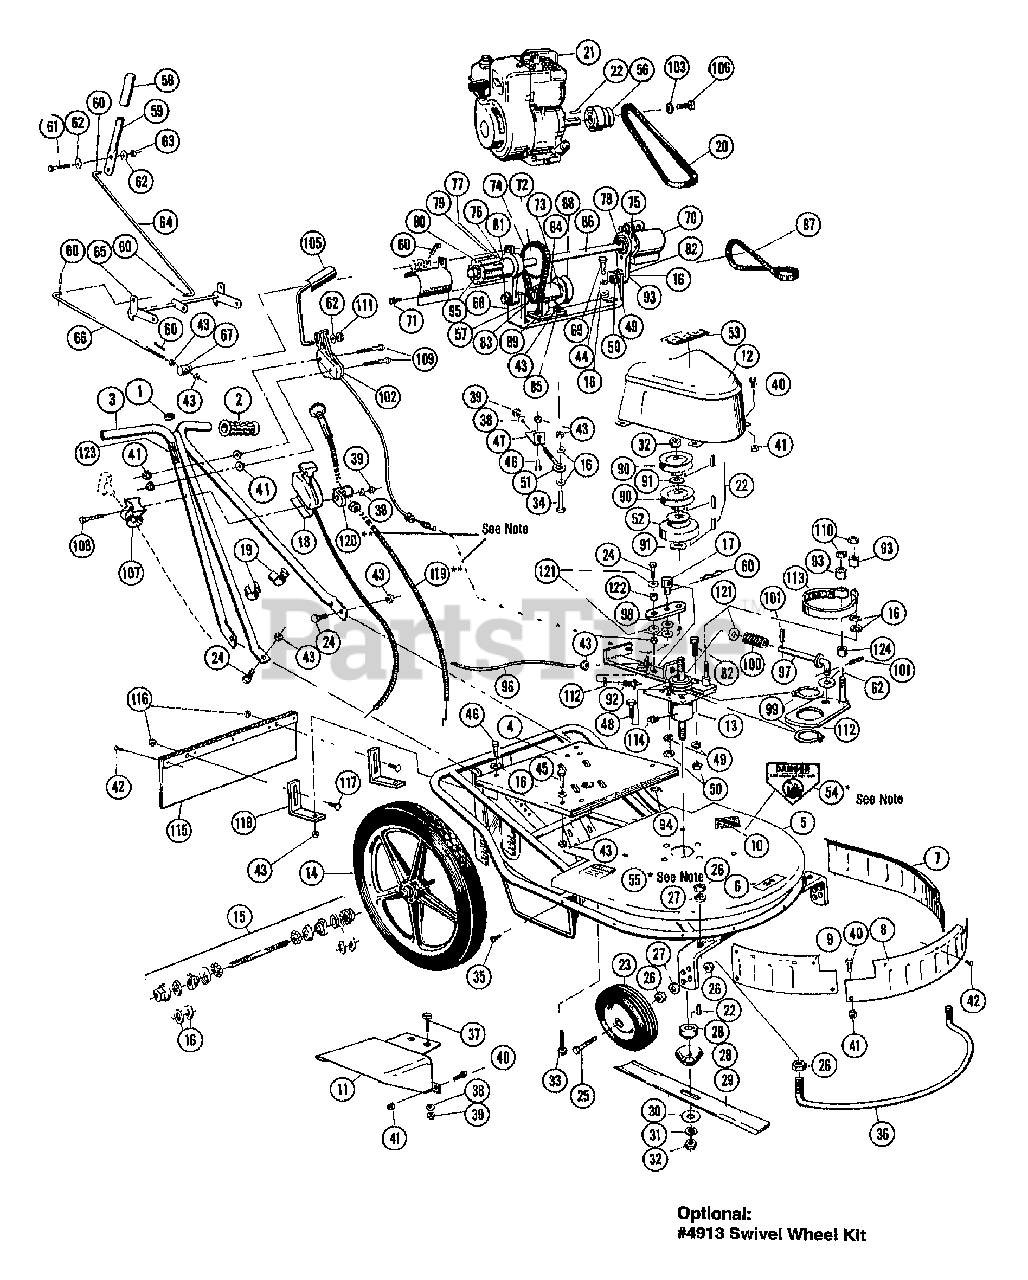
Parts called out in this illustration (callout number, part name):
1	PLUG-HANDLE
2	GRIP-HANDLE
3	ASSM-HANDLE 24"
4	BOARD-MOTOR
4	BASE-MOTOR 7HP 24"
6	CUTTING WIDTH DECAL 24"
7	GUARD-LEFT 20" & 24"
8	GUARD-FRONT 24"
9	GUARD-RIGHT
10	DECAL-CAUTION
11	DEFLECTOR-DISCHARGE
12	HOOD-MOWER
13	ASSM-24" SPINDAL
13	HOUSING-SPINDLE 24"
13	SHAFT-SPINDLE 24"
14	ASSM-WHEEL 20" W/KNOBBY
14	ASSM-WHEEL 20" W/O TIRE
14	TIRE-20" KNOBBY
15	DUST COVER SET (2)
16	WASHER-FLAT 5/16 SAE
17	PIN-CONNECTING ROD
18	CABLE-THROTTLE 24"
19	CLIP-THROTTLE CABLE
20	BELT-ENGINE #434-24"
21	ENGINE, BRIGGS 5HP #130202
21	ENGINE, BRIGGS 5HP, IC SERIES #131232
21	ENGINE, BRIGGS 7HP #170402
22	KEY-3/16-1/2
22	KEY-1/4 X L
23	WHEEL-FRONT 6"
24	SCR-HH 5/16-18X1.0 G5 ZP
25	SCR-HH 1\2X2.75
26	NUT-HEX JAM 1/2-13
27	WASHER-LK .5
28	KIT-BLADE ADAPTER
28	BLADE ADAPTER NUT
28	BEARING GUARD
29	BLADE-REPL 24" PRO MWR
30	WASHER-FLAT 5/8
31	WASHER-LK .625 ZP
32	NUT-5/8 HEX
33	SCR-HH 5/16-18X2.25 G5ZP
34	SCR-HH 5/16-18X2.5
35	SCR-#14 X .75
36	BUMPER-FRONT 24"
37	SCR-HH 1/4-20 X .625
38	WASHER-LK .25 ZP
39	NUT-HEX 1/4-20 ZP
40	SCR-HH #10-24X.375
41	NUT-3/16 HEX LOCK
42	POP RIVET
43	NUT 5/16-18
44	WASHER-LK .312 ZP
45	SCR-HH 5/16-18X1.5 G5 ZP
46	SCR-HH 5/16-18X1.75
47	BRKT-BELT ADJUST
48	SCR-HH 3/8-16X1.0 G5 ZP
49	WASHER-LOCK 3/8
50	NUT-HEX 3/8-16 ZP
51	BOLT-EYE 1/4 X 3
52	ASSM-DRUM/PULLEY
53	DECAL-"PRO"
54	DECAL-BLADE WARNING
55	DECAL-DISCHARGE CHUTE
56	CLUTCH-3/4" BORE
56	CLUTCH-1" BORE
57	SCR-SET (W02350401)
58	GRIP-POWER LEVER
59	LEVER-POWER SP
60	PIN-HITCH (24" MODEL)
61	SCR-HH 1/4-20X1.5 G5
62	WASHER-FLAT 1/4
63	NUT-LK 1/4-20
64	ROD-UPPER 22" SP/24
65	BRKT-FULCRUM 24" SP
66	ROD-LOWER 24" SP
67	CONNECTOR-PIVOT PIN
68	BRKT-LOWER DRIVE 24"
69	SCR-HH 5/16-18X1.25 G5
70	GUARD-ROLLER LT
70	GUARD-ROLLER RT
71	SCR #10-24 X .625
72	SPROCKET-36 TOOTH
73	SCR-SET 5/16 X .312
74	CHAIN-43 PITCH SP
75	ASSM-HSG ROCKER SP
75	HOUSING-ROCKER ARM SP
76	PIN-ROLL 3/16X1.25
77	PIN-DOWEL
78	PIN-ROLL 3/16X.812
79	SPRING-DOWEL RETURN
80	ROLLER-SPLINED
81	RATCHET-ROLLER DR LT
81	RATCHET-ROLLER DR RT
82	BOLT-HH 3/8-16X1.5 FTH
83	SPROCKET-10 TOOTH
84	ASSM-HSG JACKSHAFT SP
84	SPROCKET-10 TOOTH
84	HOUSING-JACKSHAFT SP
84	JACKSHAFT
85	SCR-FH 5/16-18 X 1
86	SHAFT-ROLLER DR 24" SP
87	BELT-DRIVE #284-24"
89	SHIM-CHAIN ADJUST
90	PULLEY-3 1/2 X 5/8
91	WASHER-5/8 ID X .060
92	SWITCH-ENGINE STOP
93	BUSHING-ROCKER ARM
94	NUT 5/16-18-T
95	RING-GRIP
96	ASSM-GROUND WIRE
98	LEVER-BLADE BRAKE-84
99	RING-RETAINER
100	SPRING-BLADE BRAKE
101	PIN-ROLL 1/8 X .75
102	KIT-BBC CABLE
103	WASHER-FLAT 5/16 SAE (USED ON 5HP BRIGGS)
103	WASHER-FLAT 7/16 (USED ON 7HP BRIGGS)
105	ASSM-HANDLE BLADE BRAKE
106	SCREW 5/16-24X2-1/4 HHC (USED ON 5HP BRIGGS)
106	SCREW 7/16-20X2-1/4 HHC (USED 0N 7HP BRIGGS)
107	GUIDE-ROPE (BRIGGS & STRATTON PART)
108	SCREW 1/4-20 X 2.25
109	SCREW #10-24 X 2.25
110	NUT W/NYLON INSERT 3/8-24
111	NUT-H/LK 5/16-18
112	ASSM-BRKT BRAKE BAND
113	BAND-BRAKE 3 3/4
114	GREASE FITTING
115	ASSM-REAR GUARD
116	NUT-H/LK 5/16-18 NYLOCK
117	BOLT-CARRIAGE 5/16-18X1"
118	BRKT-MOUNTING 24"
119	CHOKE CONTROL (USE ON 7HP BRIGGS ONLY)
120	BRKT-CHOKE CONTROL MTG (USE ON 7HP BRIGGS ONLY)
121	WASHER 5/16 SAE
122	BUSHING-BRAKE LEVER-84
123	DECAL-WHEEL DRIVE
124	SPACER-3/8 ID X 1/2
